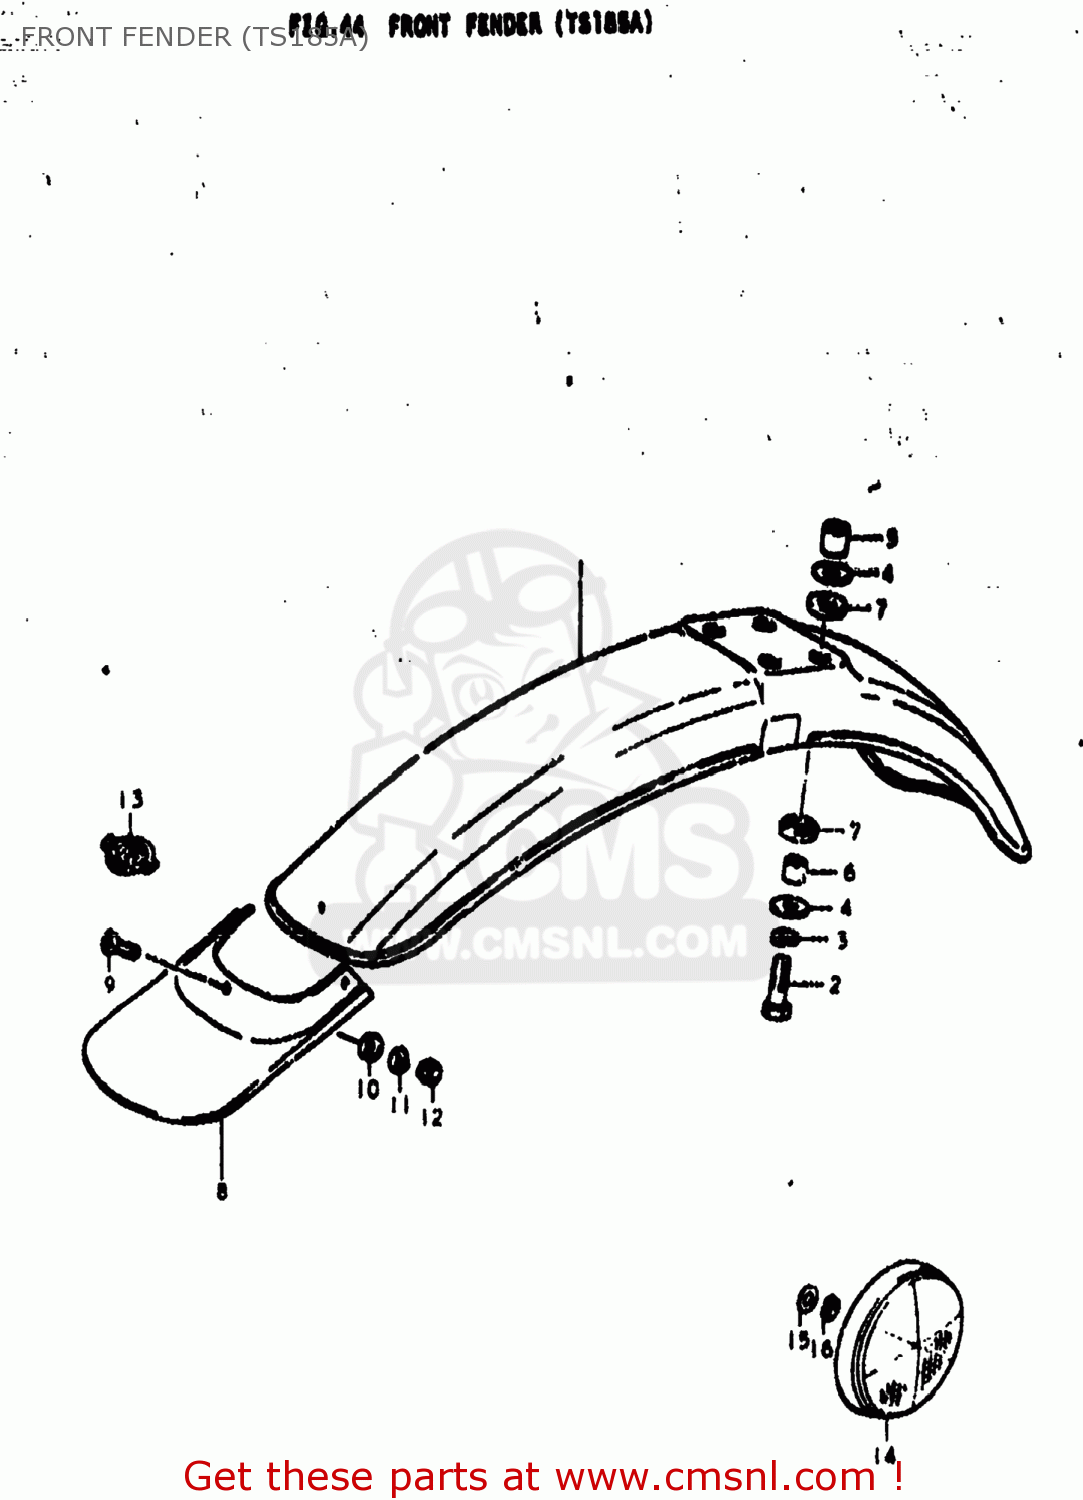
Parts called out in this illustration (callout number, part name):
1	FENDER,FRONT
2	BOLT
3	LOCK WASHER
4	WASHER (6.5X24X1.2)
5	SPACER (6.8X10X20)
6	SPACER (6.5X10.5X13.5)
7	CUSHION
8	MUD FLAP,FRONT FENDER
9	SCREW
10	WASHER
11	LOCK WASHER
12	NUT
14	REFLEX REFLECTOR ASSEMBLY
15	WASHER
16	LOCK WASHER
